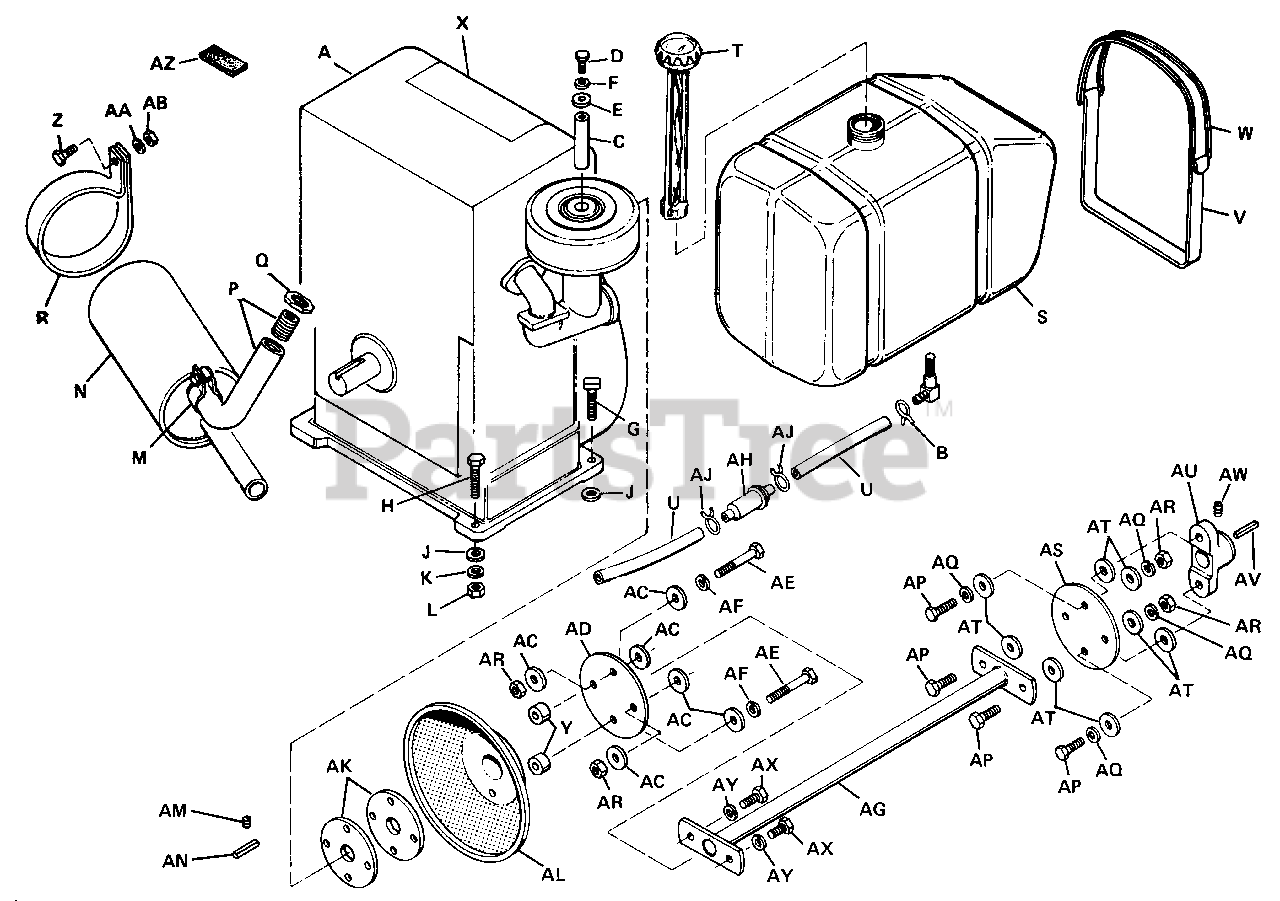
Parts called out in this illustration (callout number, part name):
B	Clamp Hose (For Service Only)
C	Air Cleaner Spacer
D	Hex Cap Screw, 1/4"-20 N.C. x 5/8"
E	Plain Washer, 1/4"
F	Lock Washer, 1/4"
G	Rec't. Head Screw, 3/8"-16 N.C. x 1-5/16"
H	Hex Cap Screw, 3/8"-16 N.C. x 1-1/2"
J	Plain Washer, 3/8" Std.
K	Lock Washer, 3/8"
L	Hex Nut Full, 3/8"-16 N.C.
M	Muffler Clamp
N	Muffler, Exhaust
P	Elbow & Nipple Assy.
R	Strap, Muffler
S	Tank, Fuel
T	Cap, Fuel Tank
U	Hose, Fuel, Flexible
V	Strap, Tank
X	Decal, Caution
Z	Hex Cap Screw, 5/16"-18 N.C. x 5/8"
AA	Lock Washer, 5/16"
AB	Hex Nut, Full, 5/16"-18 N.C.
AC	Washer, Special
AE	Hex Cap Screw, 3/8"-16 N.C. x 2-1/4" SAE Grade 5
AF	Lock Washer, 3/8"
AG	Shaft Assy., Drive
AH	Fuel Filter
AJ	Hose Clamp
AL	Screen Assy., Engine
AM	Set Screw
AN	KEY, Hi-Pro
AP	Hex Cap Screw, 3/8"-16 N.C. x 1-1/8"
AQ	Lock Washer, 3/8"
AR	Hex Nut, Full, 3/8"-16 N.C.
AT	Washer, Special
AU	Flange, Drive Shaft
AV	Key, Drive Shaft
AW	Cup Pt. Socket Head Set Screw, 3/8"-24 N.F. x 3/8"
AX	Hex Cap Screw, 3/8"-16 N.C. x 1-1/8"
AY	Lock Washer, 3/8"
AZ	Felt Gasket
